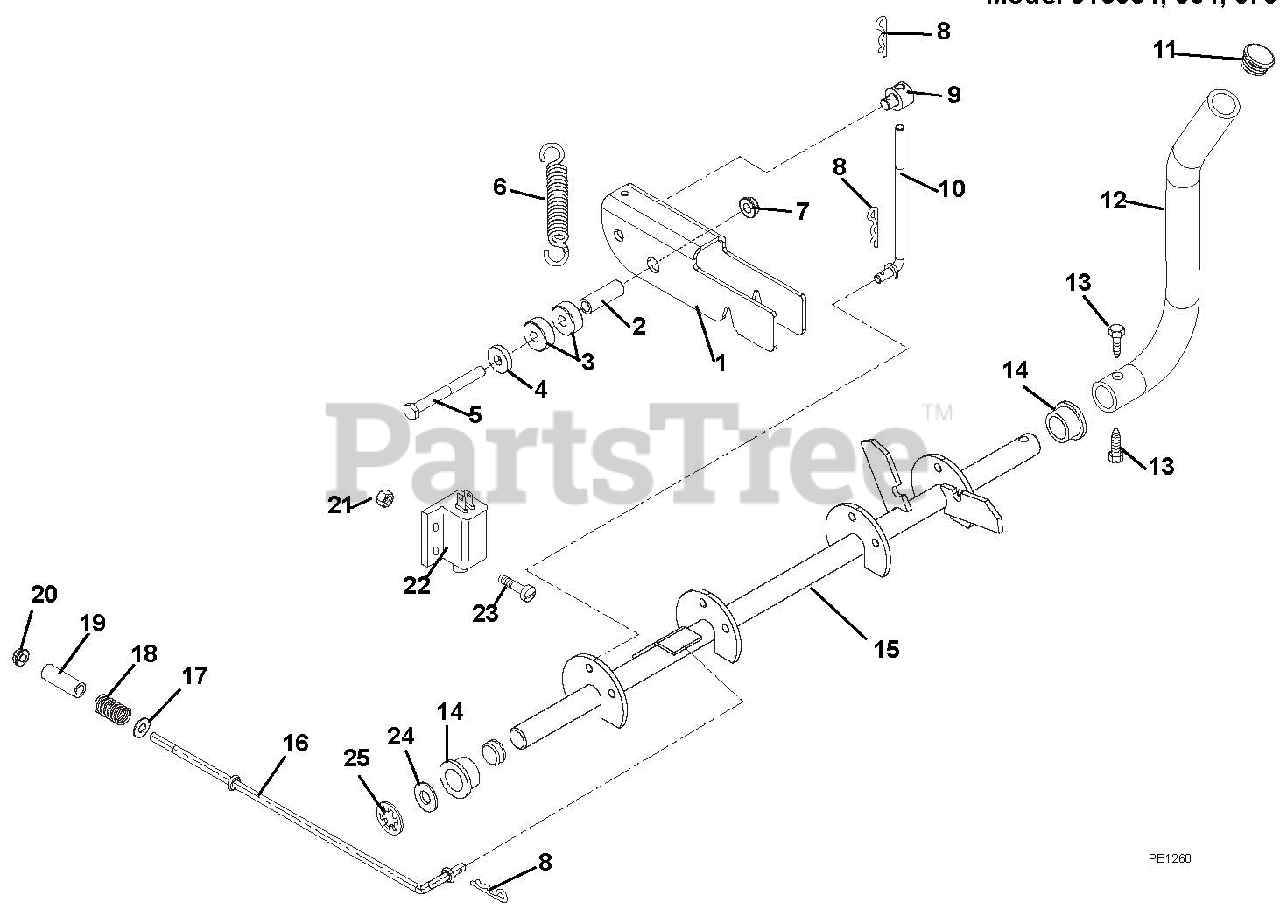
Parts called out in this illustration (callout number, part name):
1	Latch, Neutral
2	Bushing, Sleeve .334 x .502 x 1.437
4	Washer-Flat-Steel .328 x .87 x .179
5	Bolt, Hex .31-18 x 3.00 Grade 5
6	Spring, Extension .069 x .62 x 3.50
7	Nut, Flange Nyloc 5/16-18
8	Pin, Hair Int .08 x .18 x 1.18
9	Trunnion, Brake
10	Brake, Link
11	Caplug, Handlebar
12	Handle, Park Brake
13	Screw, Tapping .31-18 x .50
14	Bushing, Flanged .750 x 1.000 x .625 x 1.250
15	Weldment, Brake Shaft
16	Brake Link
17	Washer-Flat-Steel .312 x .734 x .065
18	Spring, Compression .045 x .50 x 1.187
20	Nut, Locking Nylon .250-20
21	Nut, Locking Nylon 10-24 with Insert
22	Switch, Double Pole
23	Screw, Machine 10-24 x .75
24	Washer-Flat-Steel .755 x 1.25 x .125
25	Retaining Ring 1.000 x .748
